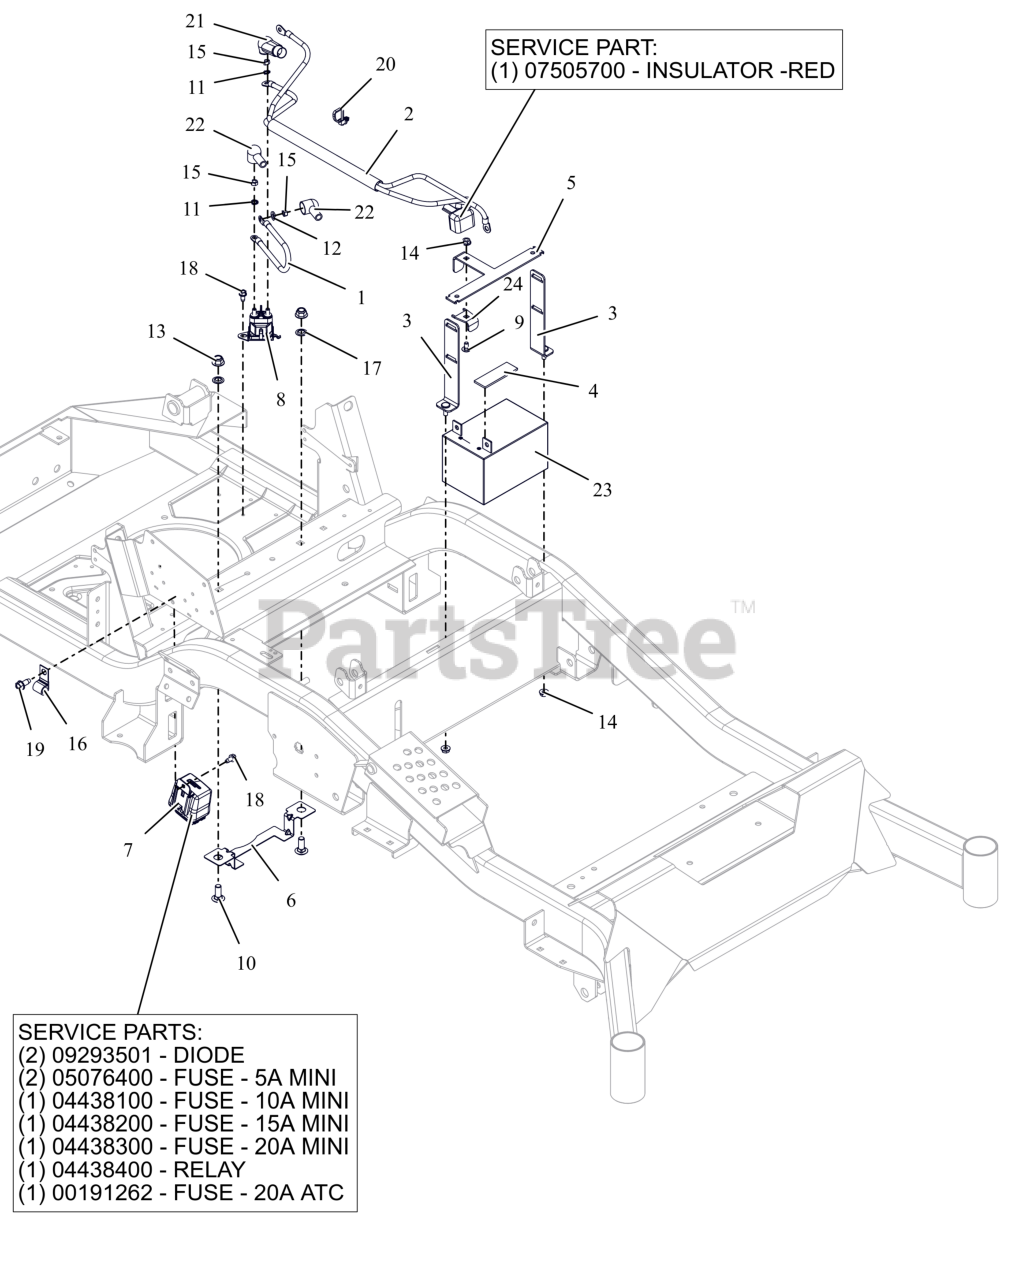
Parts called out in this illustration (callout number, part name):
1	CABLE, POS W/(2)1/4 RING 9.0LG
2	HARNESS, BATTERY HD
2	INSULATOR
3	WMT,BATTERY MOUNT HOLD DOWN
4	PAD,RBR 1.0"X3.0" W/ADHESIVE
5	BRKT, BATTERY TIE DOWN
6	GUARD, ELECTRICAL HARNESS
7	HARNESS, WIRE
7	DIODE, CONNECTOR SHELL
7	FUSE, 5 AMP MINI-ATC
7	FUSE,10 AMP MINI-ATC
7	Fuse, 15 AMP MINI-ATC
7	FUSE,20 AMP MINI ATC
7	RELAY,MICRO5 TERML W/RESISTOR
7	FUSE, 20 AMP BLADE S/O
8	SOLENOID, STARTER (SEALED)
9	BLT, RHSN .25-20X.500 G5 ZCC
10	BLT, RHSN .38-16X1.00 G5 ZCC
11	WSHR,LK-EXT.262X.502X.026 ZCC
12	WSHR,LK-REG .312X.078 ZCC
13	NUT,NYL-FLG .38-16 GF ZCC
14	NUT-LK-TOP-FLG .250-20 GF ZCC
15	NUT-STD M6-1.0 ZCC
16	J-CLAMP
17	NUT-PUSH .38 DIA. PAL ZINC
18	SCR-TAP .25-20X.50 HWH ZCC
19	SCR,TAP .312-18X.75 HWH TR ZCC
20	CABLE TIE W/ TREE (.25 HOLE)
21	BOOT, .65ID POS
22	BOOT, EYELET TERMINAL
23	BATTERY, 12V 12A -190CCA
24	BRKT, BATTERY HOLD
